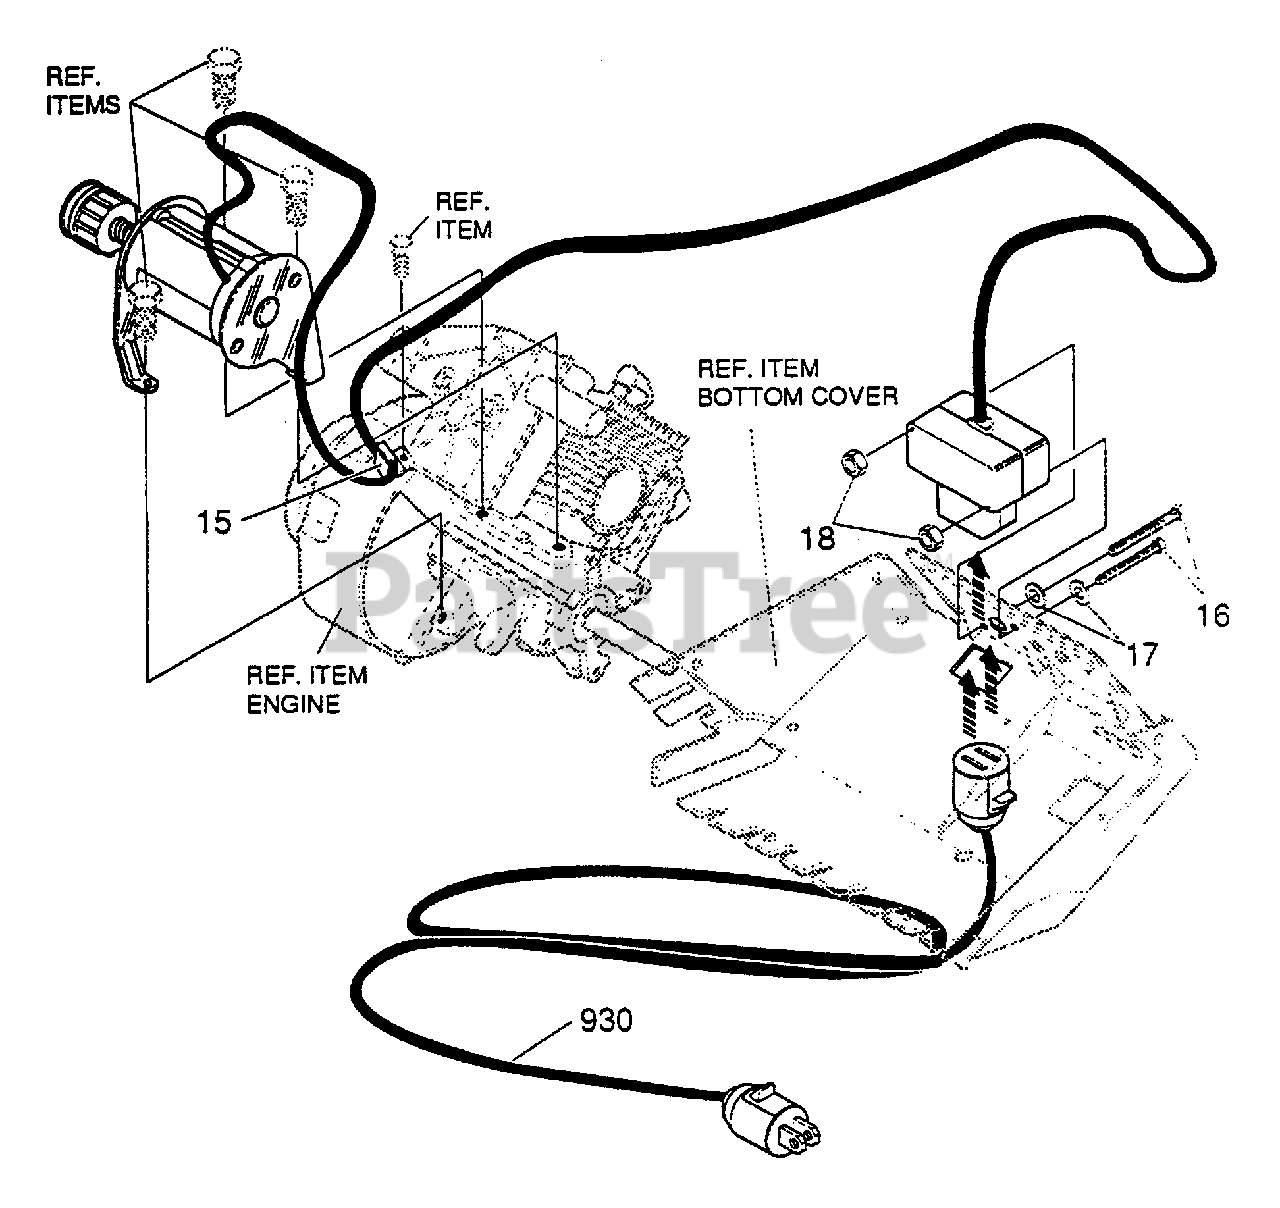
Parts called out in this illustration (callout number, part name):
15	RETAINER, WIRE
16	SCREW, #8-32 X 3.00
17	FLATWASHER .188 X .38 X .040
18	NUT, #8-32 HEX KEPS
930	CORD, EXTENSION 10 F
